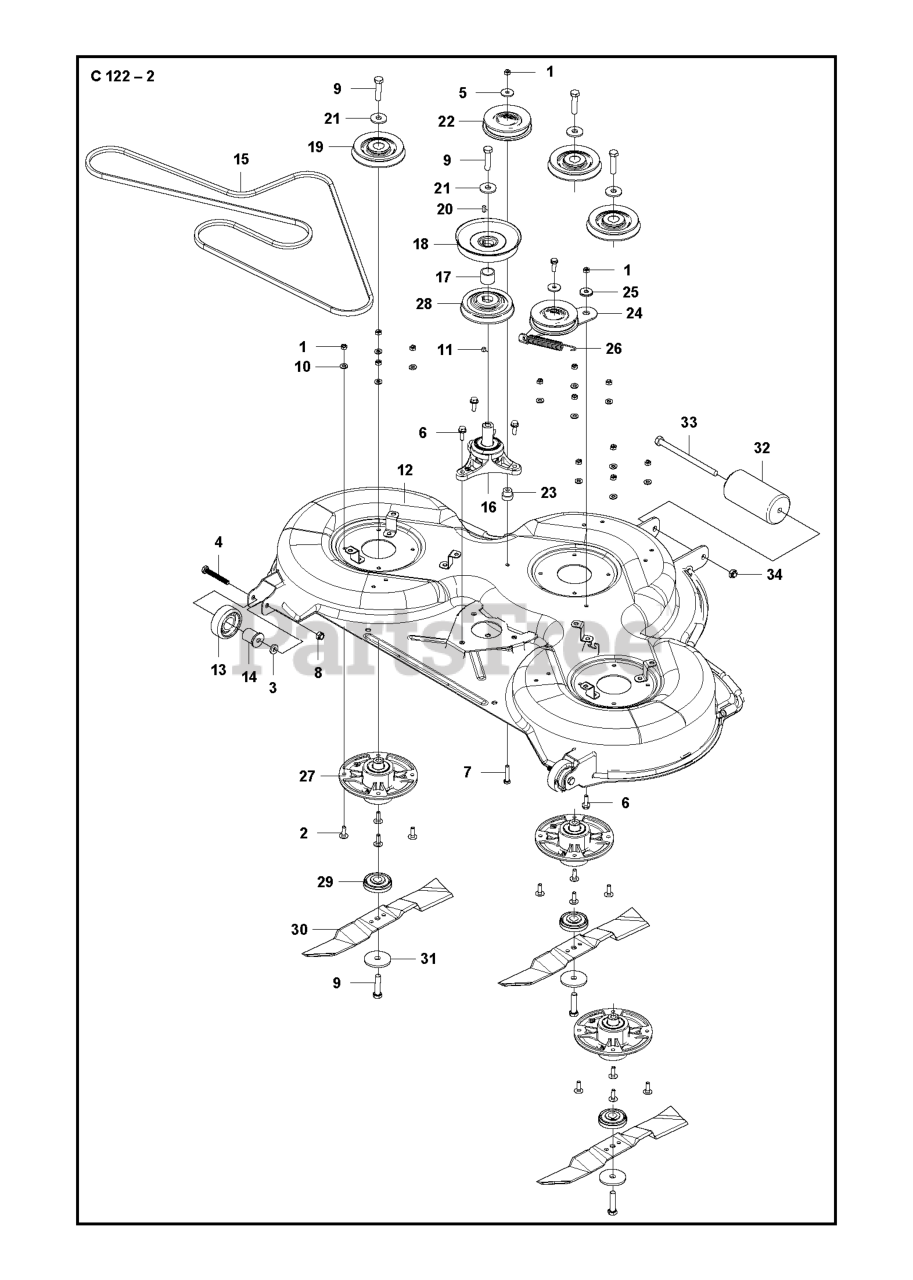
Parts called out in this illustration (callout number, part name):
1	LOCKNUT M8
6	BOLT
10	WASHER BRB 8.4X17
25	WASHER PLASTIC ASSY
32	ROLLER
